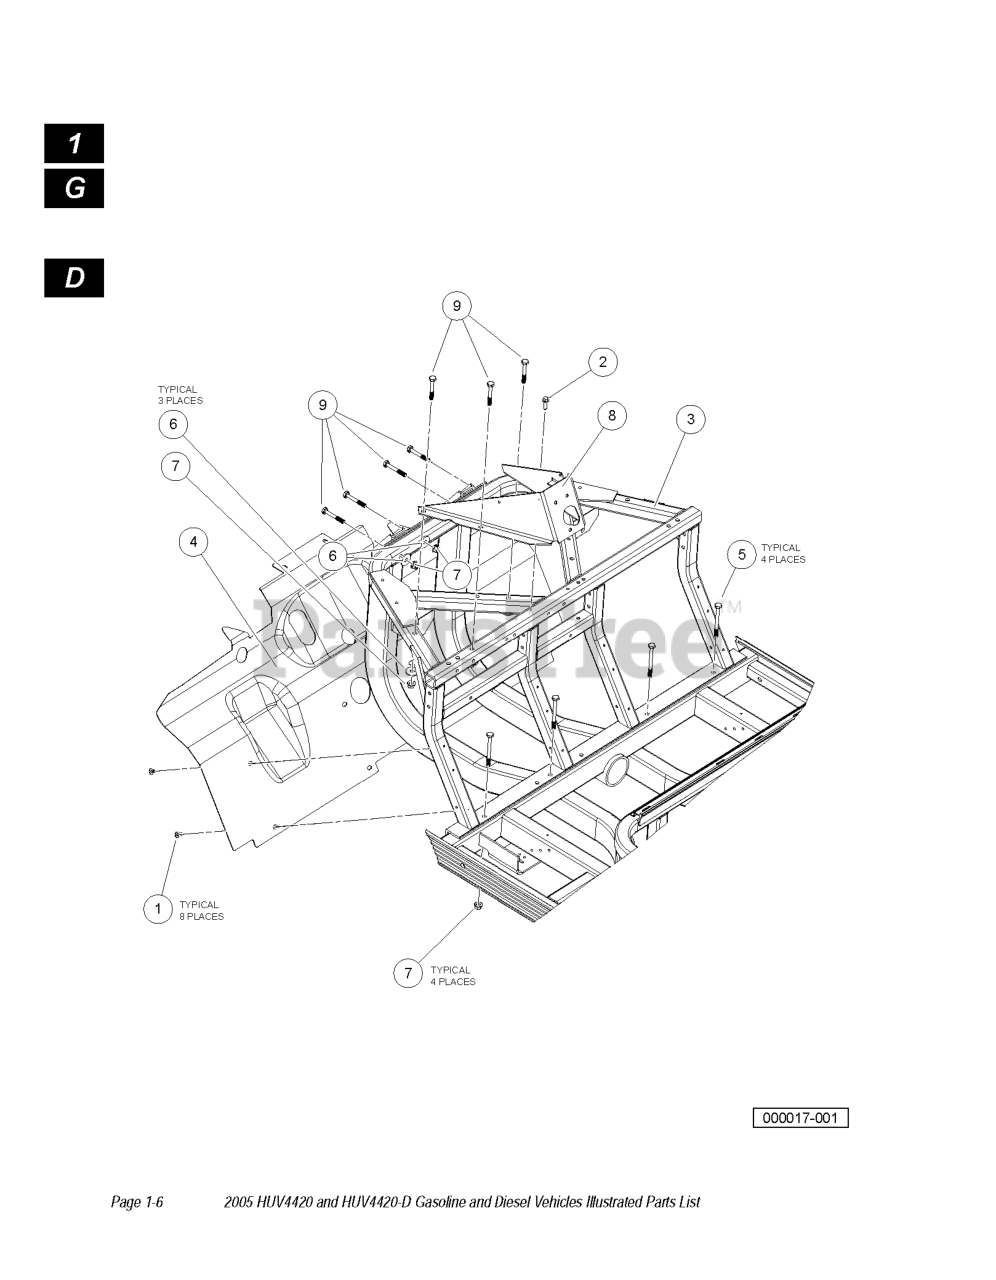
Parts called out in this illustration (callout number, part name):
1	BLIND RIVET, PUSH TYPE
2	SCREW-M8 X 1.25 30, TRI, HX F
4	GUARD, SPLASH
5	BOLT, M10 X 100, ZN-NI/BLK
6	WASHER HARD, M10
7	NUT FLG M10 X 1.5 MECH DEF
9	BOLT, M10 X 1.50 X 65
